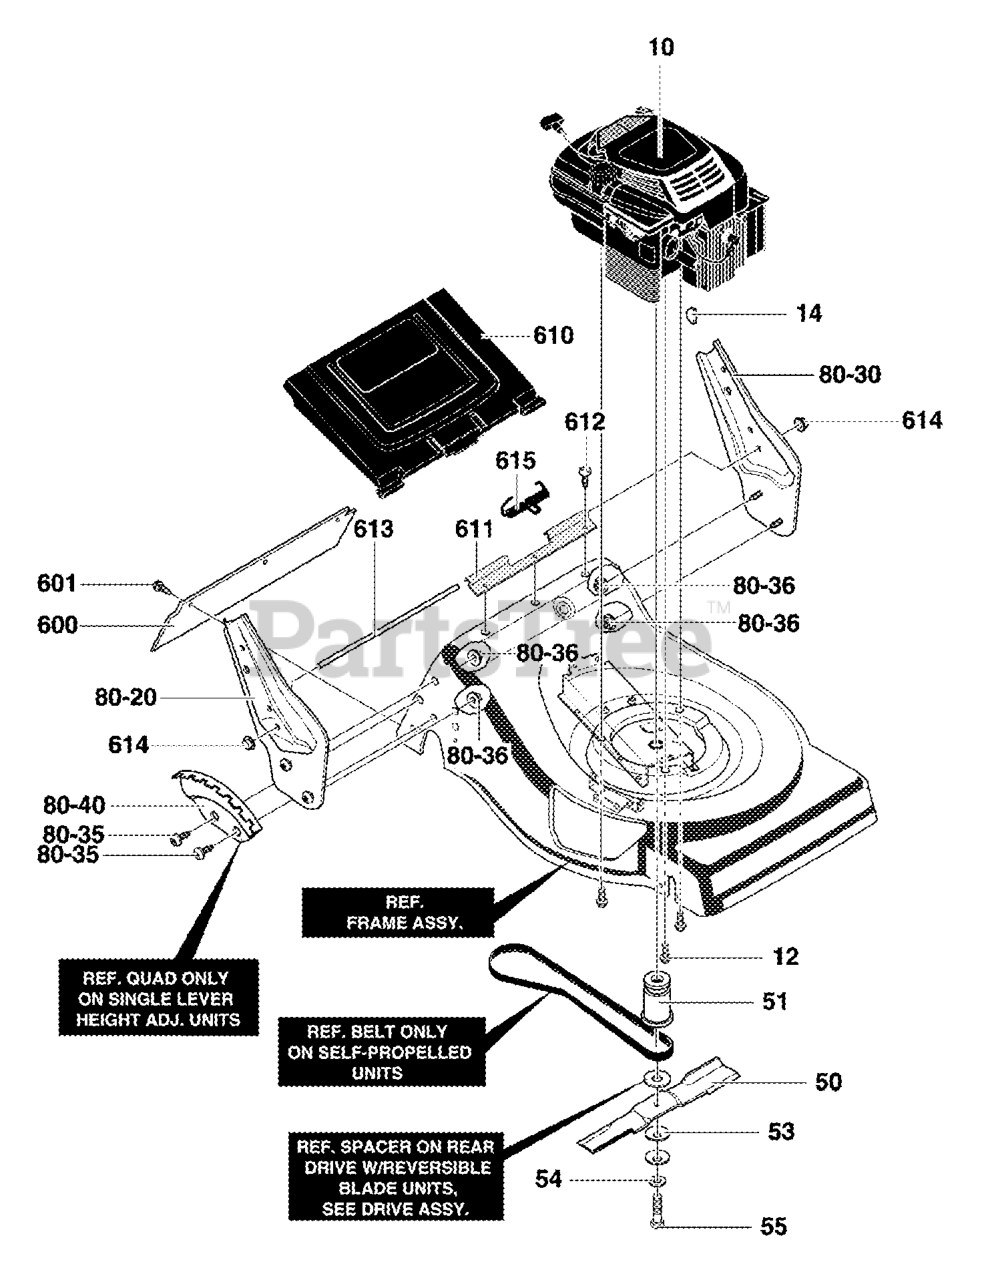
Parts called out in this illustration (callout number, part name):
10	ENGINE *
12	SCREW, 3 /8-16X1.00
14	WOODRUFF KEY 505
50	BLADE, 21" REVERSIBLE
51	ADAPTER, BLADE 21"
53	WASHER, BEVELLE
54	WASHER, FLAT .406 x .812 x .06
55	SCREW, 3/8-24 x 2.00
80-20	BRACKET, HANDLE RH
80-30	BRACKET, HANDLE LH
80-35	SCREW, 5/16-18 x 0.63
80-36	NUT, 5/16-18, HEXWDFLK WHIZ
80-40	QUADRANT, HEIGHT ADJ
600	DEFLECTOR, REAR
601	SCREW, 10-16X.50
610	DOOR, REAR 21
611	SPACER,RR DOOR
612	SCREW, 10-16X.50
613	ROD, PIVOT RR DOOR.25X18.5
614	CAP, PUSH ON
615	SPRING, TORSION
